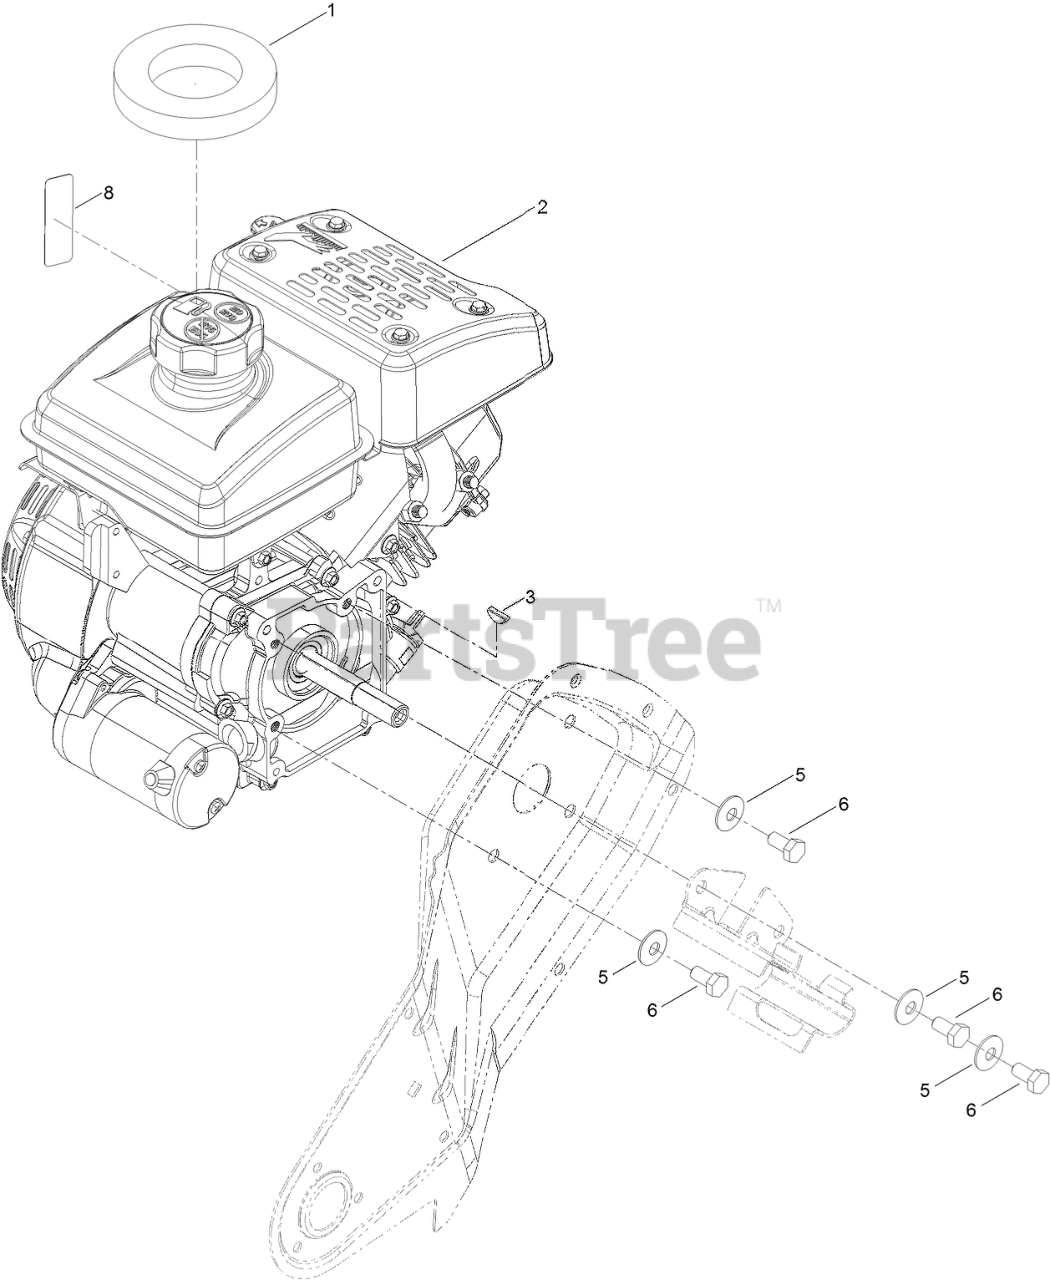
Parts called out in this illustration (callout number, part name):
1	SEAL-TANK
2	ENGINE-156FDS
3	KEY-WOODRUFF
5	WASHER-BELLEVILLE
6	SCREW-HH
8	DECAL-CONTROLS, ENGINE
